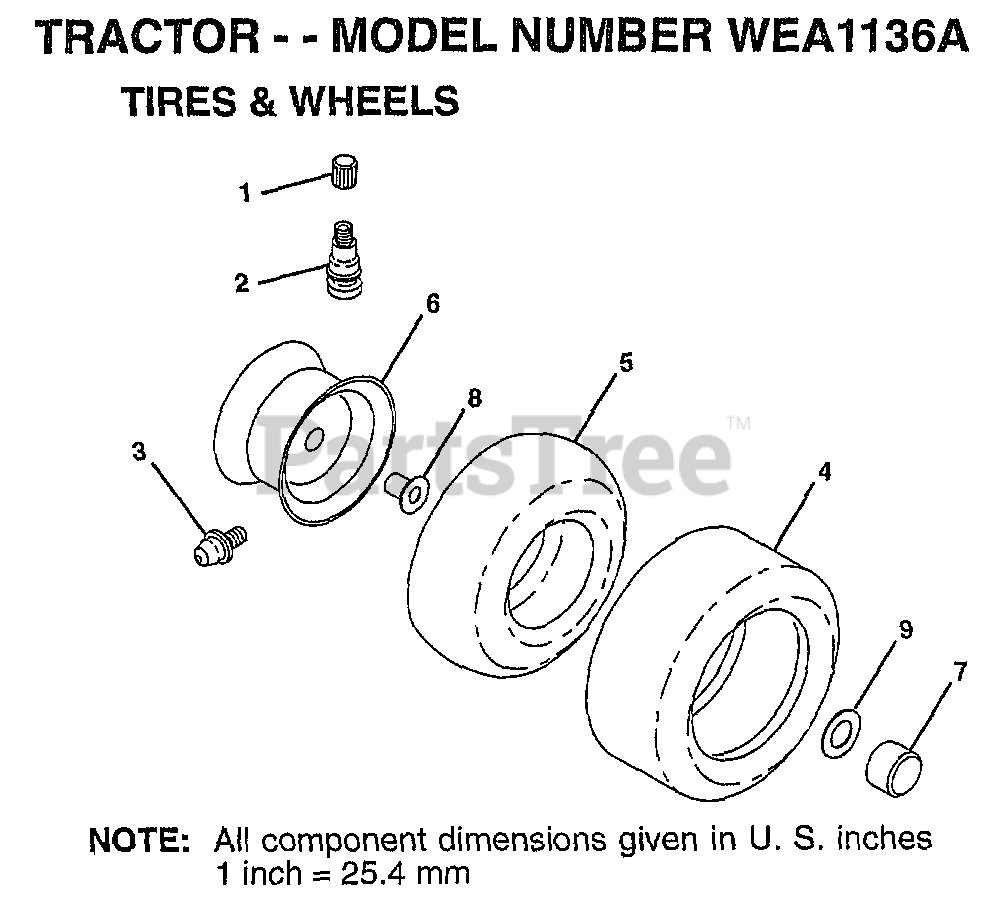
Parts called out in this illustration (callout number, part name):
1	VALVE CAP
2	VALVE STEM LT
3	FITTING LT
5	TUBE.5.3/4.5/6
5	TUBE.16X6.5/7.5-8
6	"RIM FRONT 6"""
6	"RIM ASM REAR 8"""
7	HUB CAP
8	"FLANGE, BEARING"
9	WASHER
